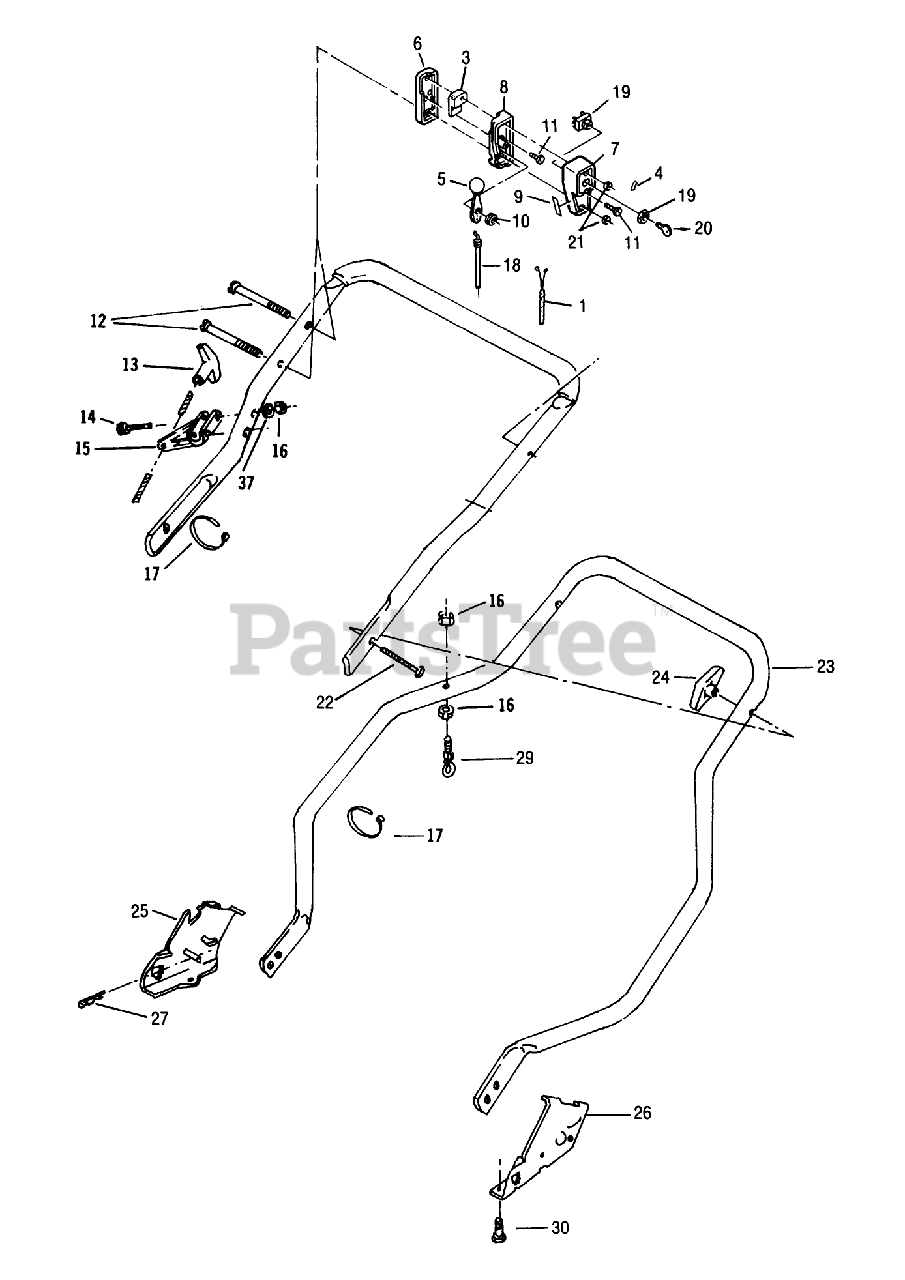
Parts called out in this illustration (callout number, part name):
1	Wire Harness Assy.
5	LEVER&KNOB AY WES
10	WASHER-SPRING
11	SCREW
12	SCREW
13	HANDLE START UM&D
16	LOCKNUT E
18	CABLE THROT WES
19	SWITCH AY
21	NUT C/LOCK E
22	BOLT QUALITY
24	NUT-WING
27	HAIR PIN
28	WASHER
29	EYE BOLT WAS MFG
30	SCREW
